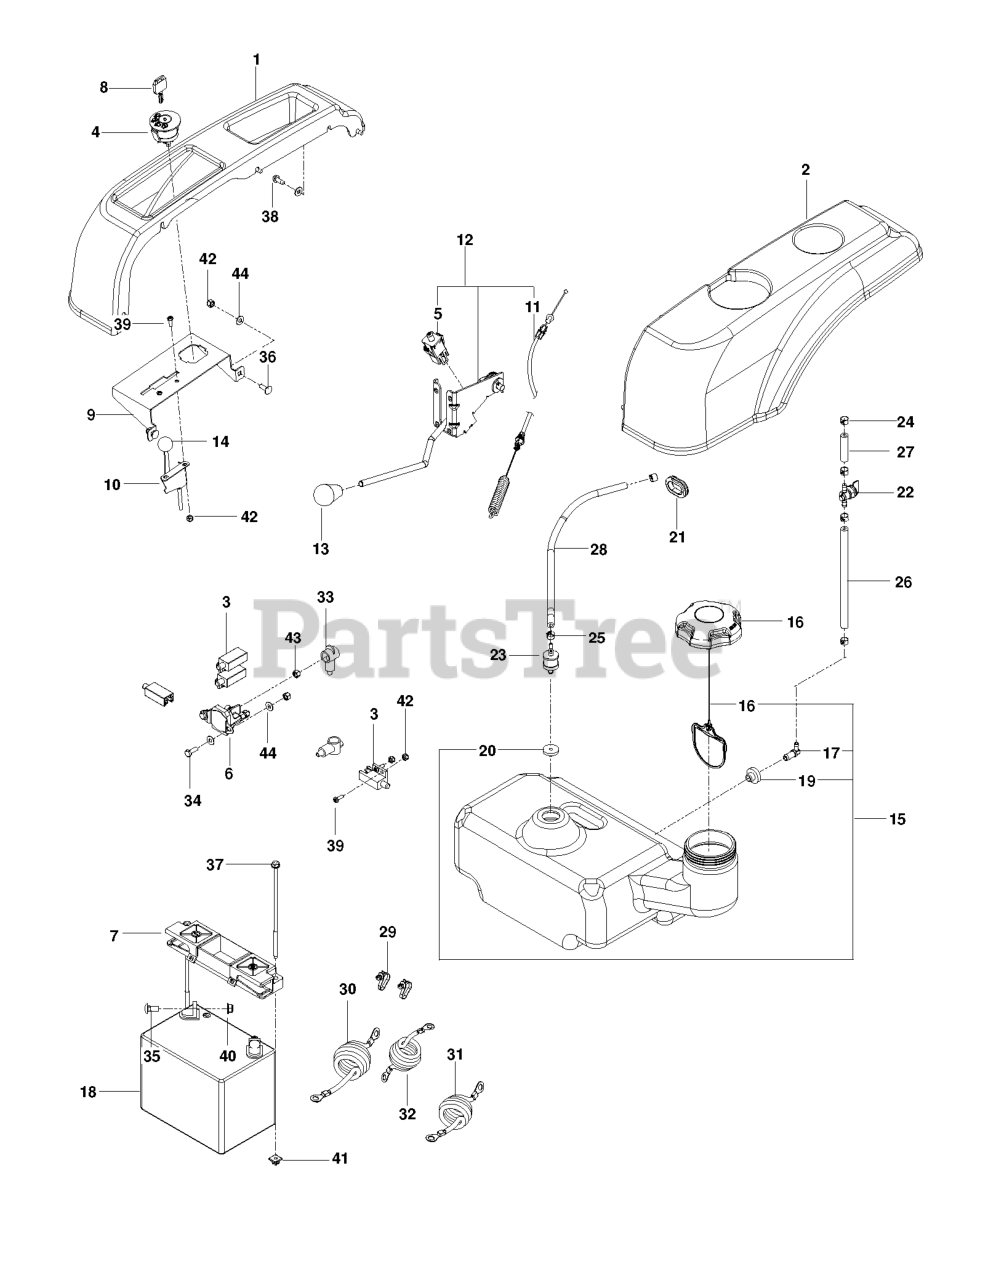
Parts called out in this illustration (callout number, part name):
1	FENDER, RZ 30/38 RT
2	FENDER, RZ 30/38 LT
3	SWITCH INTERLOCKT
4	RP IGNITION SWITCH
5	SWITCH INTERLOOK PUSH-IN
7	BATTERY HOLD DOWN
8	KEY
9	MOUNT, CONTROLS, BLK
10	CABLE, THROTTLE
11	CABLE.CLUTCH.38".SERVICE
12	ASM, CLUTCH ENGAGE W/CABLE
13	KNOB - SHIFT
14	KNOB.ROUND.BALL.BLACK
15	FUEL TANK ASM SMALL
16	CAP, FUEL
17	STEM, FUEL TANK
18	BATTERY, 12 V 330 AMP
19	RUBBER GROMMET
20	GROMMET, CHECK VALVE
21	RUBBER GROMMET
22	FUEL VALVE
23	VALVE.FUEL.CHECK
24	HOSE CLAMP
25	CLAMP, HOSE
26	HOSE 1/4 X 8
27	HOSE 1/4 X 2"
28	HOSE, FUEL, 3/16" X 20"
29	TIE, PLASTIC
30	POST.CABLE LONG
31	CABLE POSITIVE, LONG
32	BATTERY CABLE, NEGATIVE
33	TERMINAL COVER-SM
34	HCS 1/4C X 3/4 HCS
35	BOLT 5/16C X 3/4" CARRIAGE
36	RHSNB 1/4C X 3/4
37	BOLT 1/4-20 X 7.5
38	SCREW 1/4 X 5/8
39	SCREW #10-24 X 5/8
40	5/16-18 NYLOC FLANGE NUT
41	PUSH NUT-NYLON
42	NUT 10-24 NYLOC
43	NUT.1/4-20.HEX.NYLOC.ZD
44	WASHER 1/4 SAE
